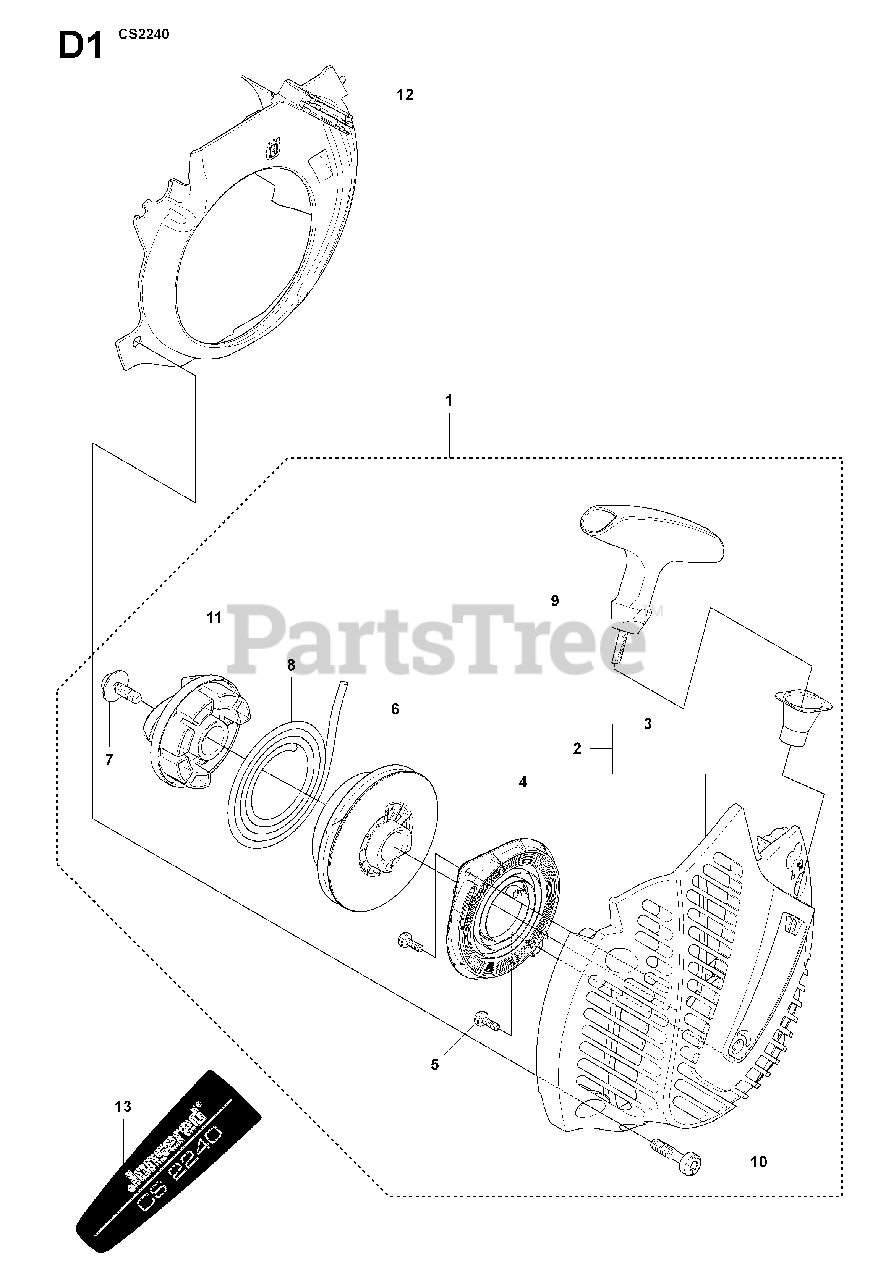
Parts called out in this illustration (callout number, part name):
2	STARTER HOUSING
4	SPRING CASSETTE ASSY
5	SCREW
6	STARTER PULLEY
7	SCREW
8	STARTER ROPE
9	STARTER HANDLE
10	SCREW
12	%COOLING AIR CONDUCTOR
